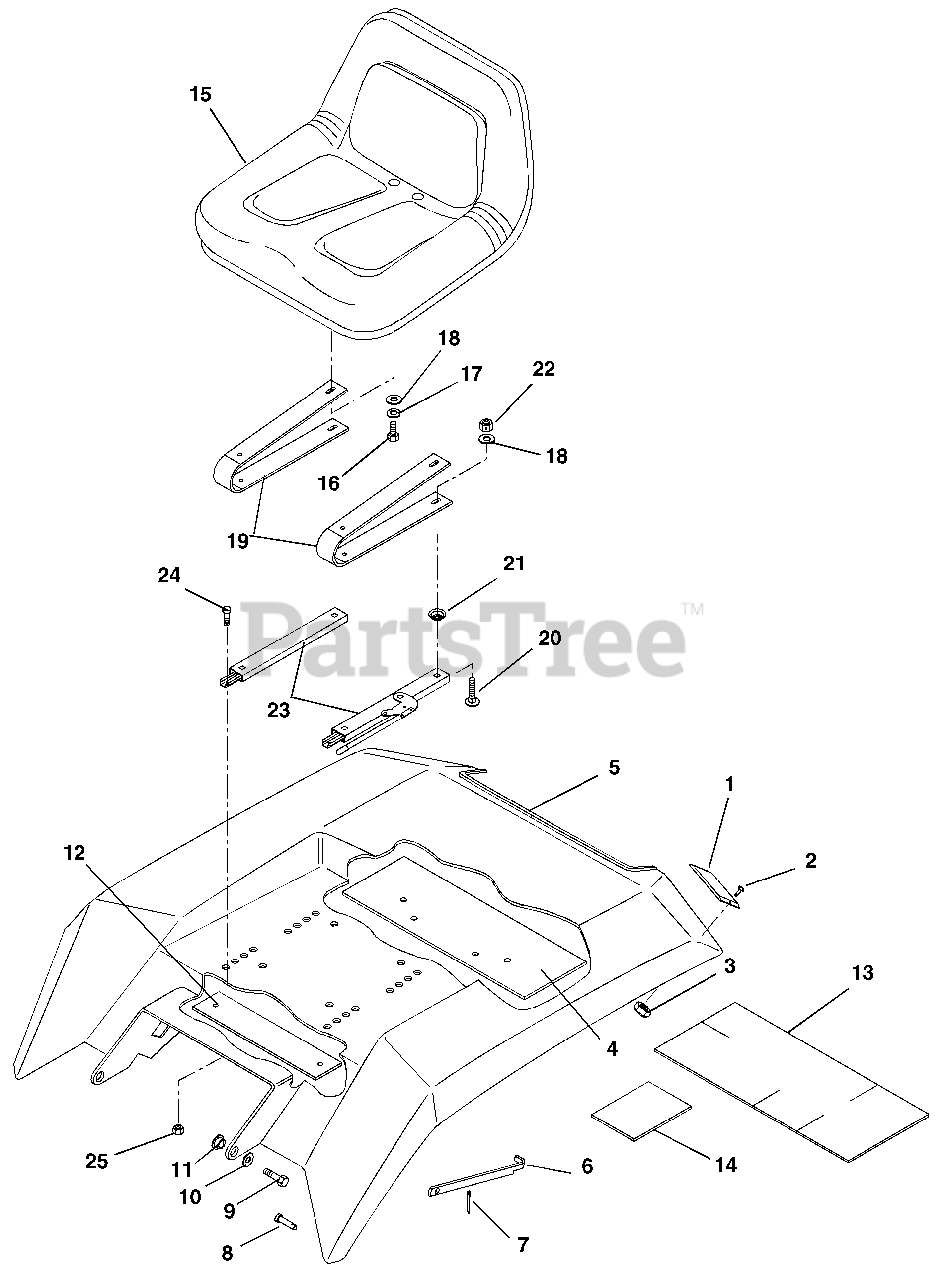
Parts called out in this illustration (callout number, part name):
1	Reflector
2	Screw-Machine 10-24 x .50 Hex Washer Head
3	Nut-Locking 10-32 Nylon
4	Bracket, Seat Support
5	Weldment, Seat Pan Head Notched
6	Strap, Fender Hold-Up
7	Pin-Cotter .06 x .75
8	Pin-Clevis .25 x .406
9	Bolt-Hex .38-16 x 1.00 Grade 5
10	Washer-Flat-Steel .41 x .81 x .065
11	Bushing-Flange .41 x .88 x .27 x .14
12	Bracket, Seat
13	Heat Shield 30.5 x 14
14	Heat Shield 12 x 9
15	Seat, V-560 High Back
16	Bolt-Hex .31-18 x .75 Grade 5
17	Washer-Locking .31 x .078 Regular
18	Washer-Flat-Steel .34 x .69 x .065
19	Spring, Seat
20	Bolt-Round Head Square Neck .31-18 x 1.00 Grade 5
21	Spacer, Seat Slider
22	Nut-Locking-Center .31-18
23	Slides, Seat
24	Screw-Cap .31-18 x .875 Grade 5
25	Nut-Hex .31-18
